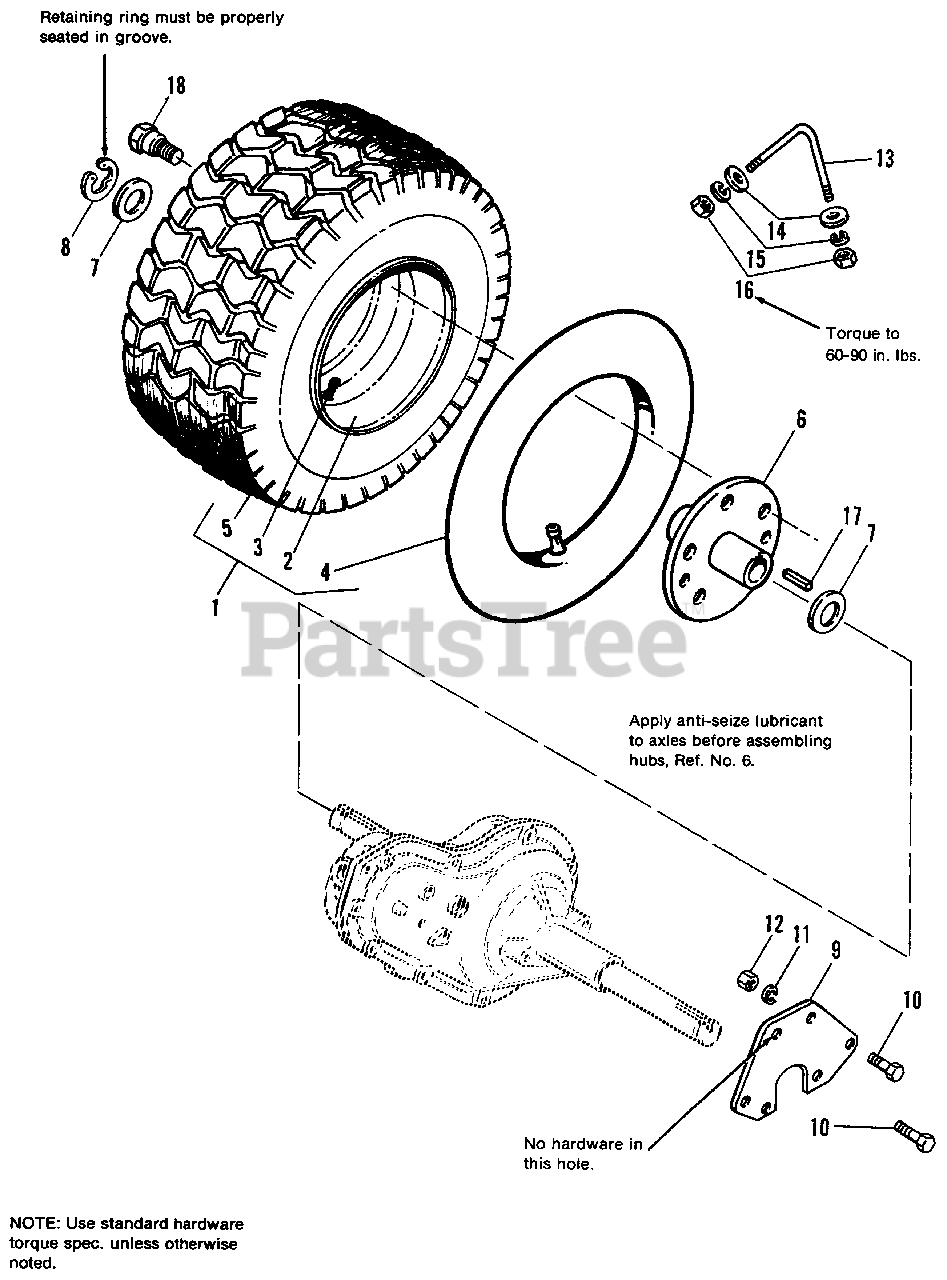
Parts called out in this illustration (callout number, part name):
1	WHEEL & TIRE ASSY., Turf, 23 x 10.50-12 (Includes Ref. No. 2, 3, 4 & 5)
1	WHEEL & TIRE ASSY., L.H., Agriculture (Includes Ref. No. 2, 3, 4 & 5)
1	WHEEL & TIRE ASSY., R.H., Agricultural (Includes Ref. No. 2, 3, 4 & 5)
3	VALVE STEM & CAP
4	TUBE, (Service Only) 23 x 10.50-12
5	TIRE, Turf, Carlisle Turf Saver, 23 x 10.50-12
5	TIRE, Agricultural, 23 x 10.50-12
6	HUB ASSY., Rear Wheel
9	BRACKET, Support
10	SCREW, Whizlock, 3/8-16 x 1
11	LOCKWASHER. 3/8
12	NUT, Hex, 3/8-16
13	BOLT, Axle
14	WASHER, 5/16
15	LOCKWASHER, 5/16
16	NUT, Hex, 5/16-18
17	KEY, 1/4 x 1/4 x 2-1/4
